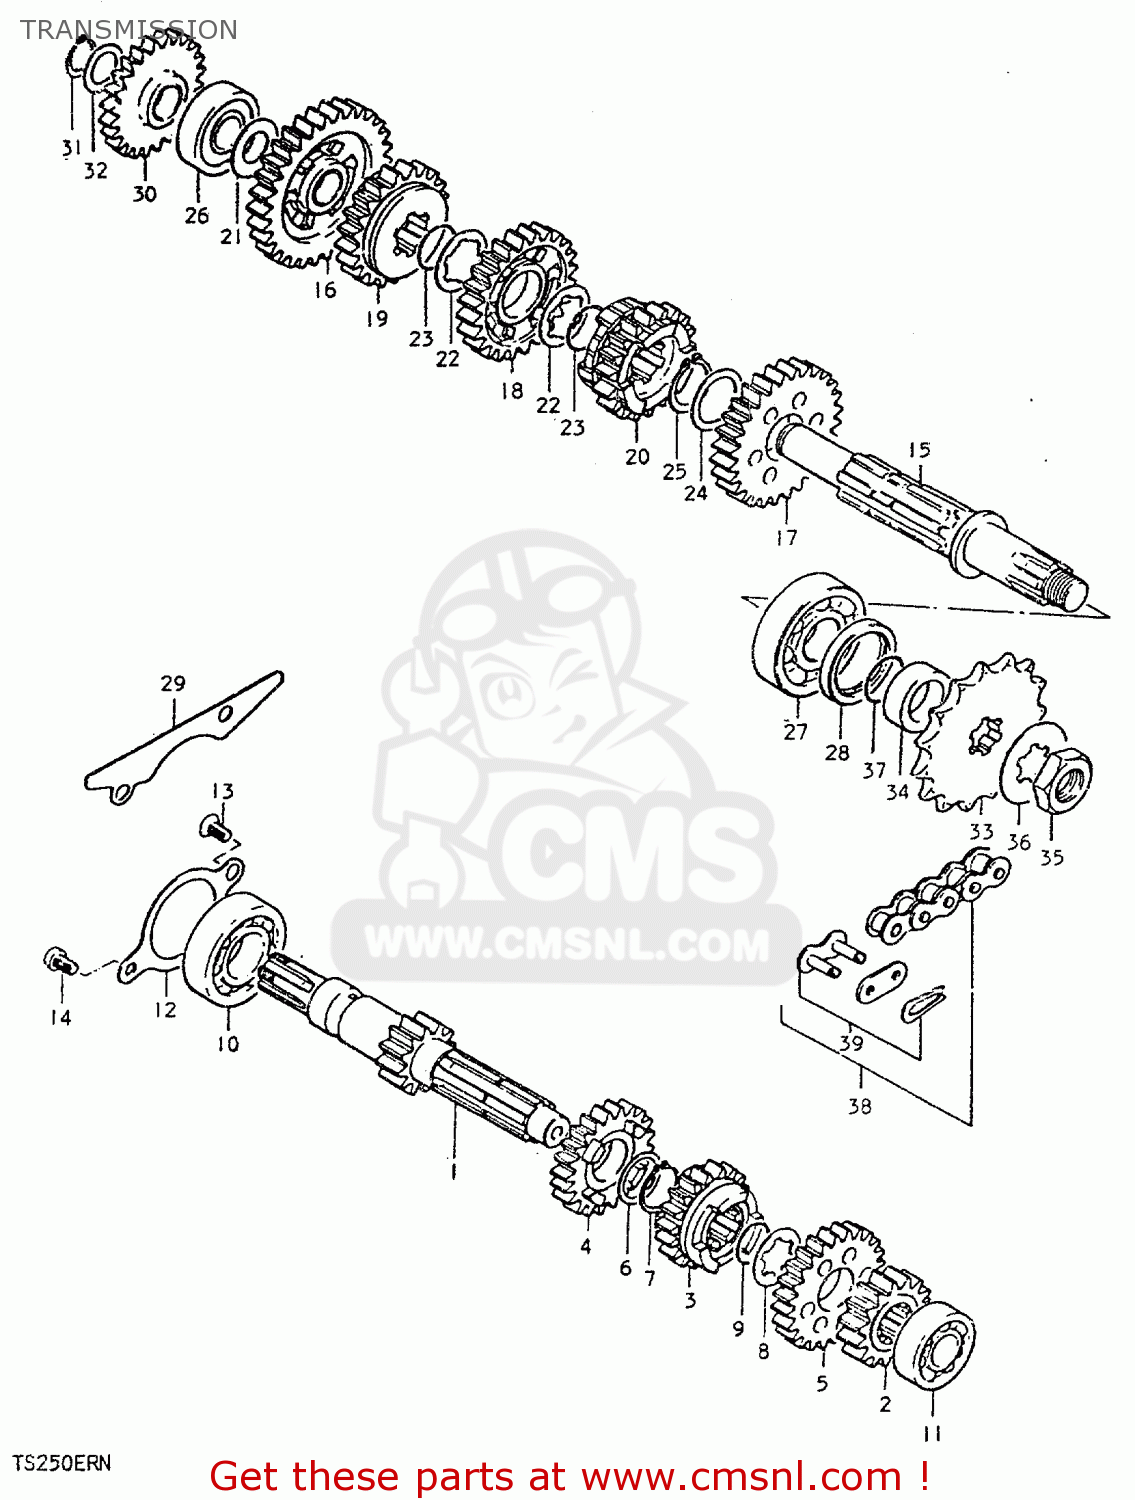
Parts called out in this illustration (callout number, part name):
1	SHAFT,COUNTER
2	GEAR,SECOND DRIVE
3	GEAR,THIRD DRIVE
4	GEAR,FOURTH DRIVE
5	GEAR,FIFTH DRIVE
6	SHIM
7	CIRCLIP
8	WASHER,LOCK
9	CIRCLIP
10	BEARING
11	BEARING
12	PLATE,COUNTERSHAFT BEARING
13	SCREW
14	SCREW 6X12
15	SHAFT,DRIVE
16	GEAR,FIRST DRIVEN
17	GEAR,SECOND DRIVEN
18	GEAR,THIRD DRIVEN
19	GEAR,FOURTH DRIVEN
20	GEAR,5TH DRIVEN
21	WASHER,THRUST
22	WASHER,LOCK
23	RING,SNAP
24	WASHER
25	CIRCLIP
26	BEARING
27	BEARING
28	SEAL,OIL(32X42X6)
29	PLATE,OIL RESERVOIR
30	GEAR,KICK STARTER IDLE
31	CIRCLIP
32	WASHER
33	SPROCKET,ENGINE
34	SPACER(22X32X11.5)
35	NUT
36	WASHER,LOCK
37	O RING(D:1.7,ID:22)
38	CHAIN,DRIVE #525TR-10
39	JOINT ASSEMBLY,CHAIN
